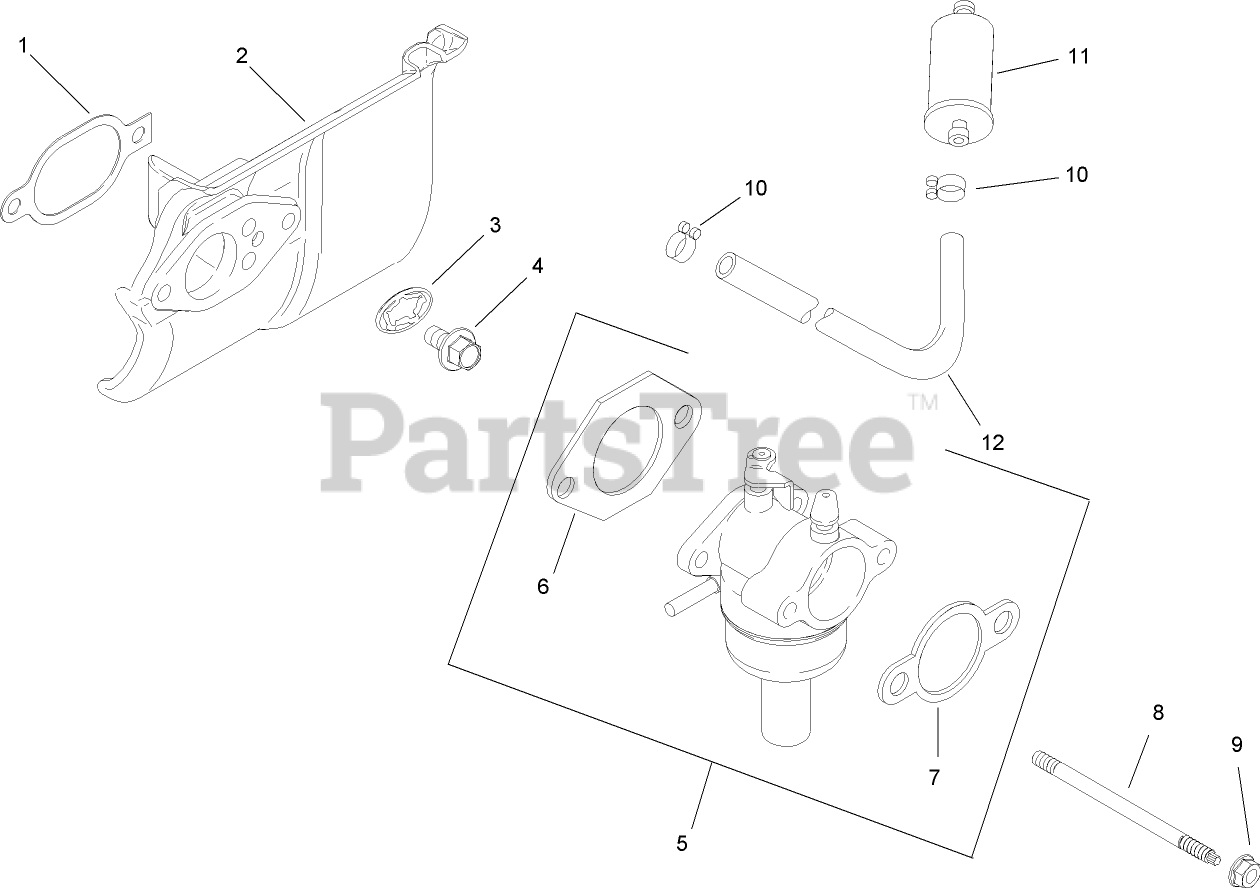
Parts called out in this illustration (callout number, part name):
1	Gasket-Deflector, Heat
2	Deflector-Heat
3	Washer-Lock, Internal Tooth (1/4)
4	Screw-Flange, Hex (M6x1.0x20)
5	Carburetor ASM w/Gaskets (Includes?6-7)
6	Gasket-Base, Air Cleaner
7	Gasket-Carburetor
8	Stud-Mounting, Carburetor (M6X1.0X100)
9	NUT-FLANGE (M6X1.0)
10	CLAMP-HOSE, SPRING (1/2)
11	FILTER-FUEL
12	Line-Fuel, 7 Inch
13	Float Repair Kit
14	Carburetor Repair Kit
15	Solenoid Repair Kit
16	Bowl Replacement Repair Kit
17	High Altitude Kit (5, 000 ft)
18	High Altitude Kit (10, 000 ft)
19	Tie-Wire
